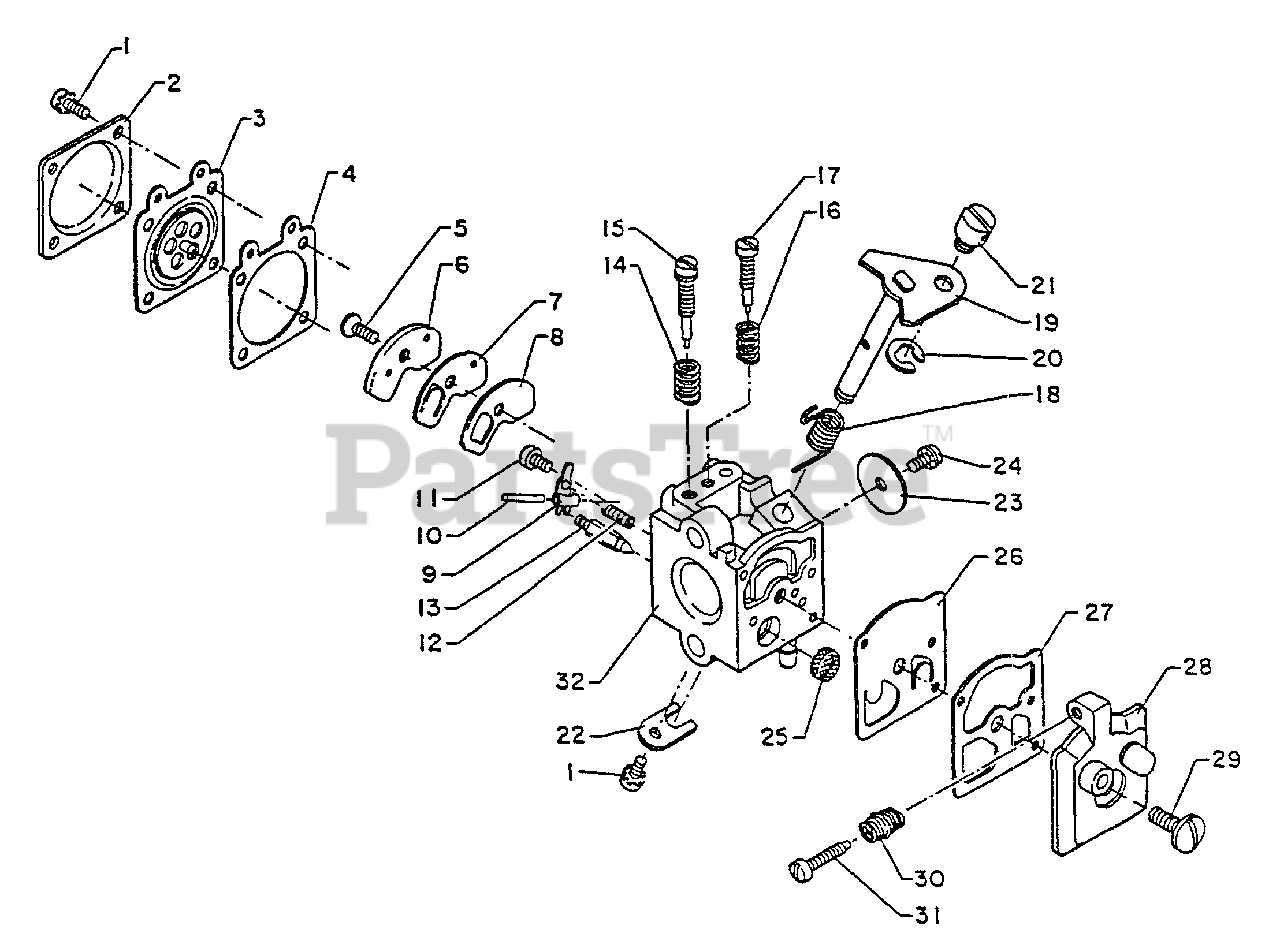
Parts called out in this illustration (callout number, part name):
1	SCREW
2	COVER, METERING
3	DIAPHRAGM, METERING
4	GASKET, METERING
5	SCREW, CIRCUIT PLATE
6	PLATE, CIRCUIT
7	DIAPHRAGM, CIRCUIT PLATE
8	GASKET, CIRCUIT PLATE
9	LEVER, METERING
10	PIN, METERING LEVER
11	SCREW, METERING LEVER PIN
12	SPRING, METERING LEVER
13	VALVE, INLET NEEDLE
14	SPRING, HIGH SPEED NEEDLE
15	NEEDLE - HIGH SPEED
16	SPRING, LOW SPEED NEEDLE
17	NEEDLE - LOW SPEED
18	SPRING, THROTTLE RETURN
19	SHAFT, THROTTLE
20	RING, RETAINING
22	CLIP, THROTTLE SHAFT
23	VALVE, THROTTLE
25	STRAINER
26	DIAPHRAGM, PURGE
27	GASKET, PURGE
28	COVER, PUMP
29	SCREW, PUMP COVER
30	SPRING, IDLE ADJUST
31	SCREW, IDLE ADJUST
32	BODY, CARBURETOR
